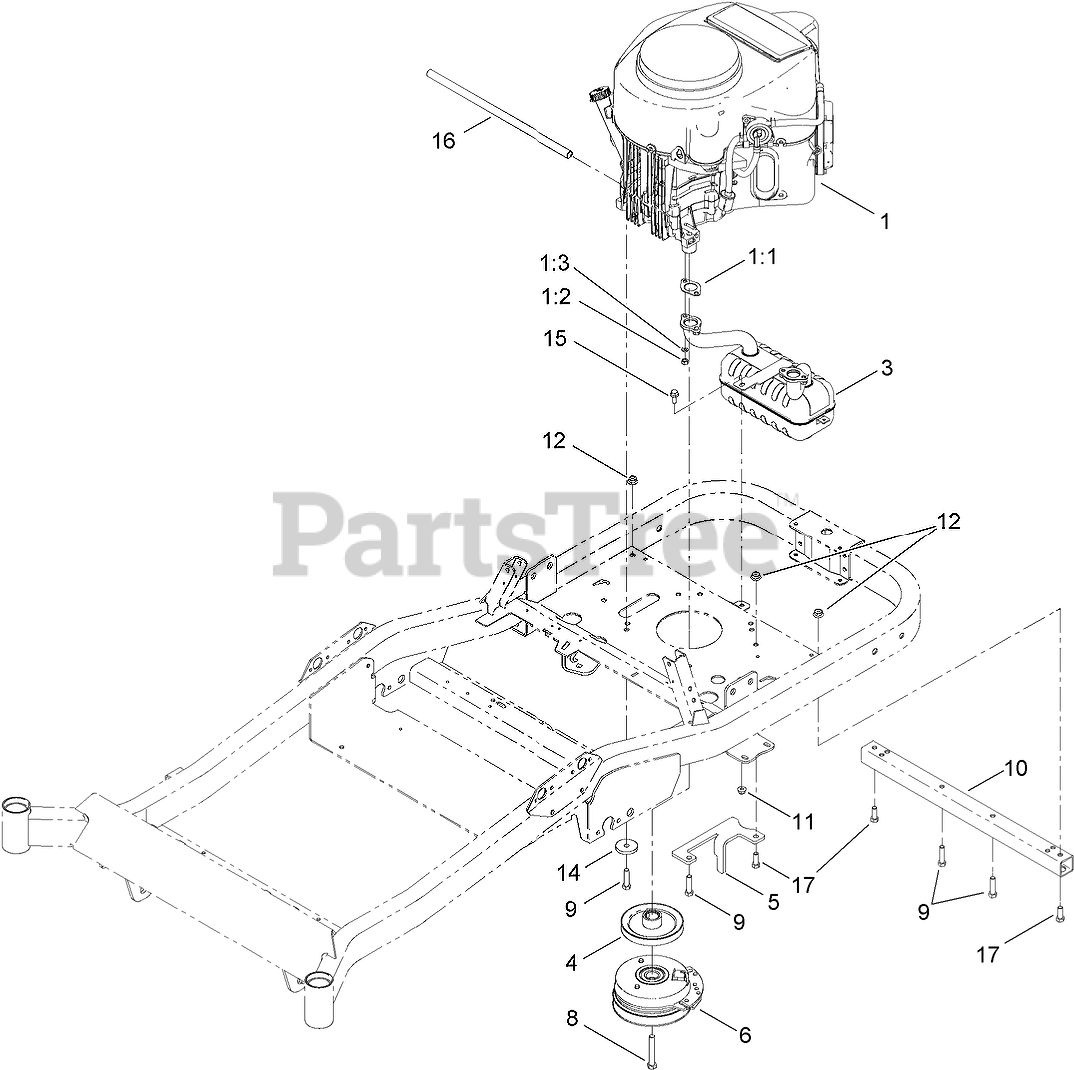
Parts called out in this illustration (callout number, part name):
1:1	GASKET-EXHAUST
1:3	WASHER-LOCK
3	MUFFLER-KAWASAKI TWIN
4	PULLEY-ENGINE
5	BRACKET-STOP, PTO
6	CLUTCH-PTO
8	SCREW-HH
9	BOLT-HH
10	TUBE-STIFFENER
11	NUT-HF, NI
12	NUT-HF, NI
14	WASHER-PLAIN
15	SCREW-HHF
16	TUBE-DRAIN, OIL
17	SCREW-HH
